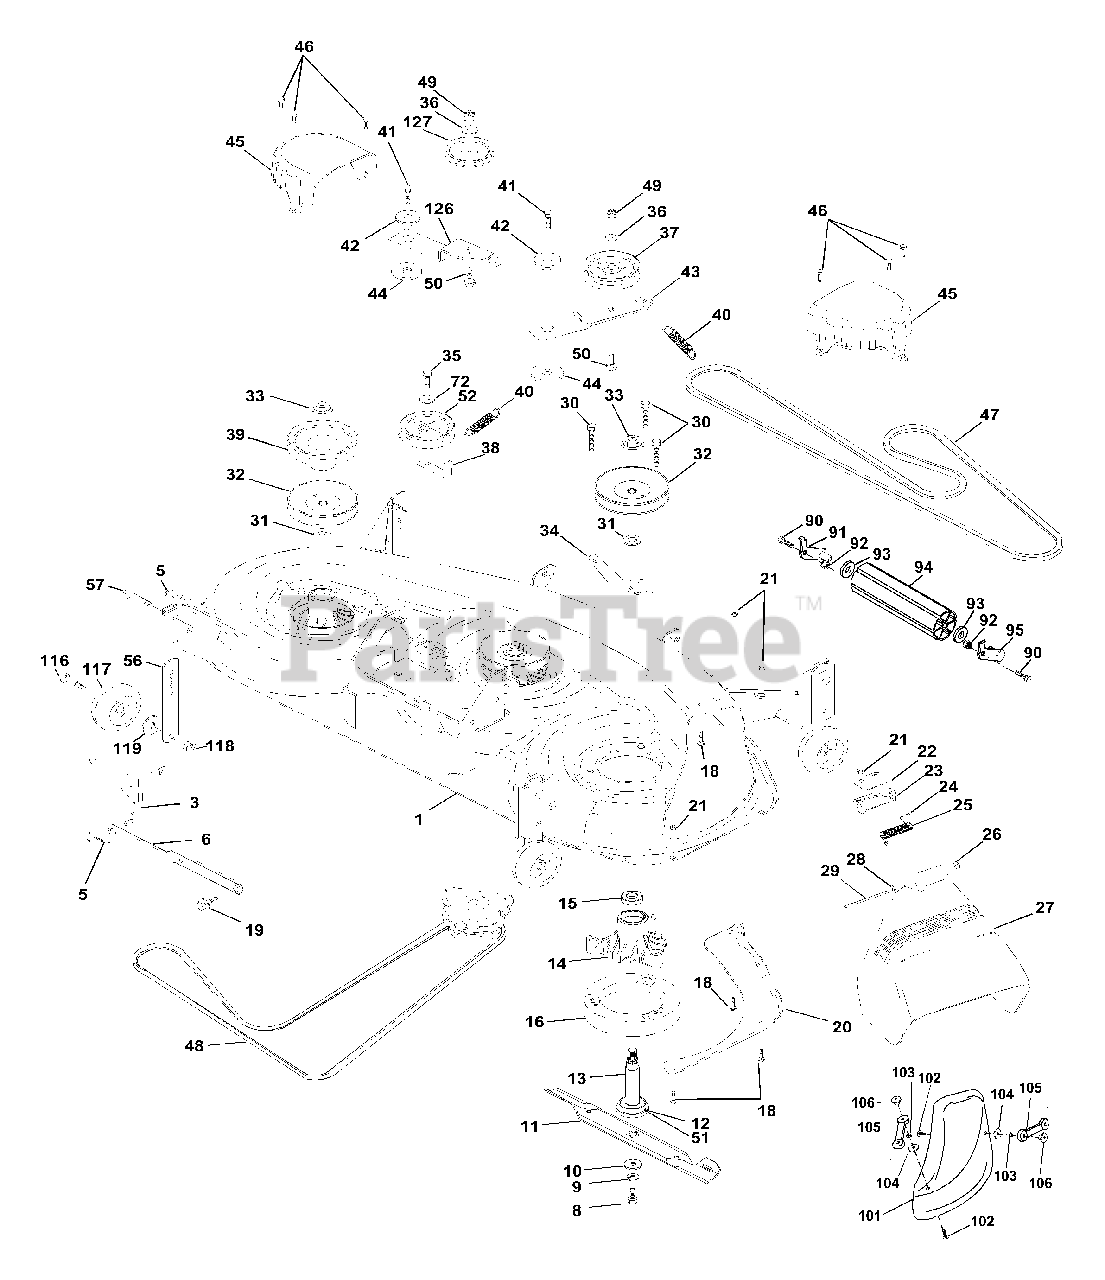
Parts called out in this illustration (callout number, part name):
1	Deck Weldment Mower 46 98
3	Bracket Asm., Sway Bar
5	Retainer Spring
6	Arm, Suspension, Rear (Sway Bar)
8	Bolt, Patched 3/8-24 x 1-1/4 Gr. 8
9	Washer, Lock Hvy., Unplated 3/8
10	Washer, Hard Blade, Mower Vented
11	Blade, 46" Hi Pref.
12	Bearing, Ball, Mandrel #6204
13	Shaft Asm. w/Lower Bearing
14	Housing, Mandrel
15	Bearing, Ball, Mandrel
16	Stripper, Mower Round
18	Bolt, Carriage 5/16-18 x 5/8
19	Bolt, Hex Head, Shoulder 5/16-18
20	Baffle, Vortex Mower 46"
21	Nut, Crownlock 5/16-18 UNC
22	Stiffiner, Bracket
23	Bracket, Deflector
24	Cap, Sleeve
25	Spring, Torsion, Deflector
26	Nut, Push
27	Deflector Clipping
28	Washer 11/32 x 5/8 x 16 Ga.
29	Rod, Hinge
30	Screw, Thdroll Washer Head
31	Washer, Spacer Mower Vented
32	Pulley, Mandrel
33	Nut, Flg. Top Lock Cntr. 9/16
34	Anchor, Spring Deck 46"
35	Screw, Thdroll 3/8-16 x 1-3/4 Tytt
36	Washer 13/32 x 13/16 x 16 Ga.
37	Pulley Idler Flat
38	Keeper, Belt, Idler
39	Pulley, Idler, Driven
40	Spring, Secondary 44/46/50 Vent
41	Screw 3/8-16 x 1-1/4
42	Spacer, Retainer
43	Arm, Idler Secondary
44	Washer,Hardened
45	Cover, Mandrel Deck
46	Screw, Thdroll. 1/4-20 x 5/8
47	V-Belt, Mower, Secondary
48	V-Belt, Mower, Primary
49	Nut, Crownlock 3/8-16 UNC
50	Bolt, Carriage 3/8-16 x 1-1/2 Gr. 5
51	Washer, Felt
52	Pulley Idler 46 Pri Drive 97
56	Bar Adjusting Gd Whl
57	Pin Head Rivet
72	Washer 13/32 x 1 x 16 Ga.
90	Bolt Hex Hd Fin 3/8-16 x 1
91	Bracket Asm Nr Lh
92	Nut Lock Hex 3\8-16
93	Washer 17/32 x 7/8 x 16 Ga
94	Nose Roller
95	Bracket Asm Nr Rh
101	Cover Mulcher
102	Screw Truss Hd Phil 10-24 x 5/8
103	Washer Lock #10
105	Latch Asm Mulch
106	Nut Weld
116	Bolt, Shoulder
117	Gauge Wheel, Wide
118	Nut, Centerlock 3/8-16 UNC
119	Washer 3/8 x 7/8 x 14 Ga.
126	Arm, Idler, Primary Deck 46"
127	Pulley, Idler, V-Groove Dim. 4.25
